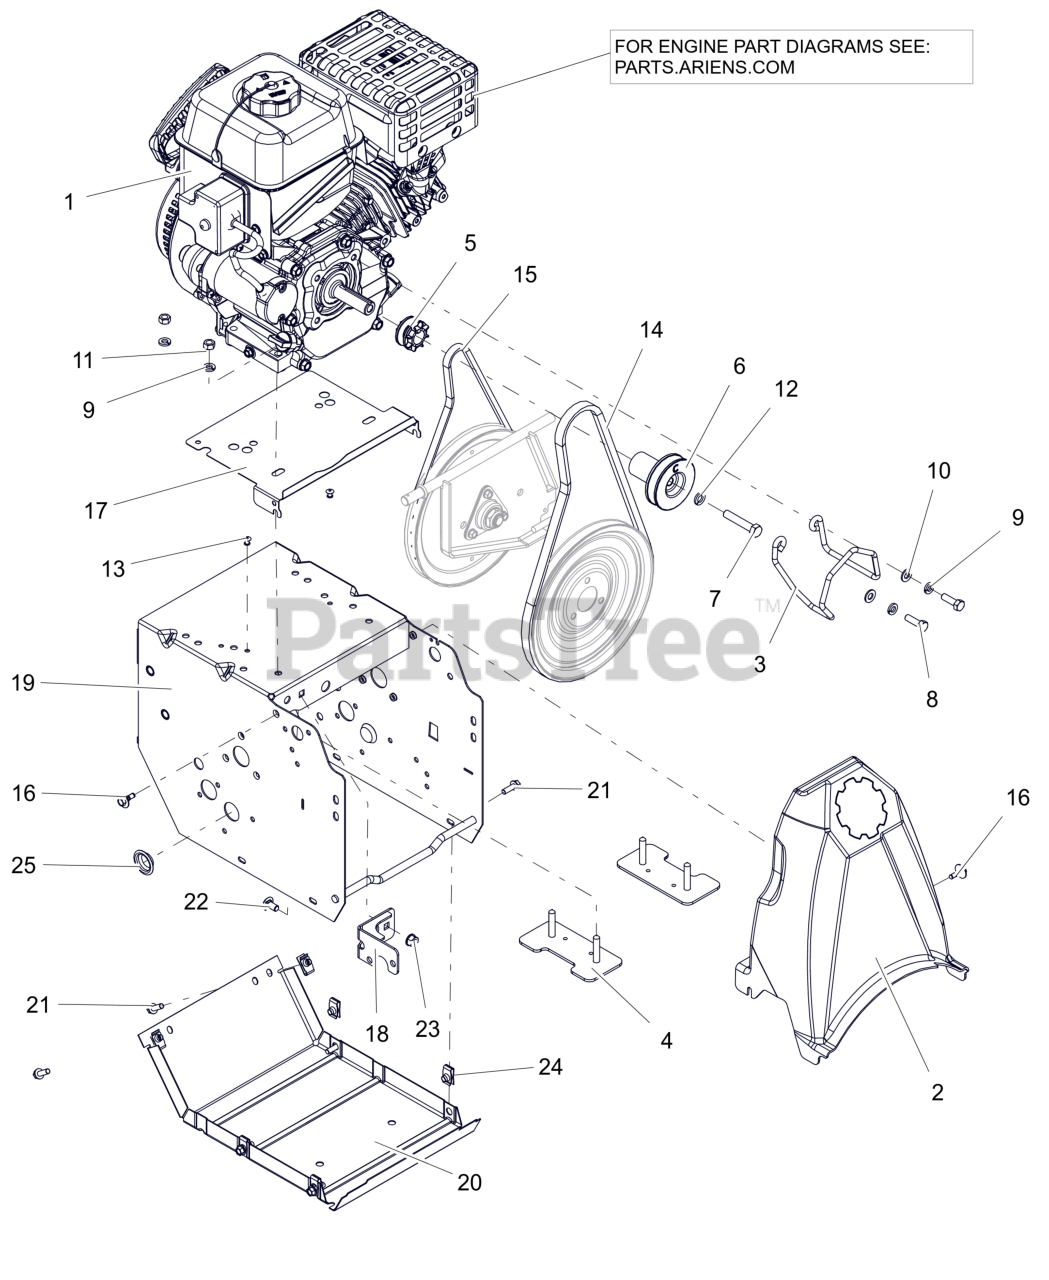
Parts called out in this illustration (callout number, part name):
1	Engine, AX179 120v Gen II
2	COVER- CLASSIC BELT
3	FINGER, BELT
4	STRAP, ENGINE BOLT-WELDMENT
5	SHEAVE, TRACTION
6	SHEAVE, ATTACHMENT SINGLE GRV
7	BLT, HEX .38-24X2.00 G5 ZCC
8	BLT, HEX 0.3125-24X1 G5 ZCC
9	WSHR, LK-HVY .312X.097 ZCC
10	WSHR,FLT .344X.688X.065 ZCC
11	NUT, HEX .312-18 ZCC
12	WSHR,LK-REG .375X.094 ZCC
13	RVT, POP .1875 ZCC
14	V-BELT, HA-RAW EDGE
15	V-BELT, 3L-WRAPPED
16	SCR-TAP .25-20X.5 CAPTIVE
17	BAFFLE, COMPACT
18	WELDMENT, FRAME BRACKET
19	FRAME, MAIN
20	COVER, BOTTOM
21	BLT, HWH .25-20X.75 G5 ZCC
22	BLT, RHSSN .31-18X.625 G5 ZCC
23	NUT-LK-TOP-FLG .312-18 GF ZCC
24	NUT-RTNR .25-20X.56
25	PLUG, HOLE - 1.00" FLEXTEMP
